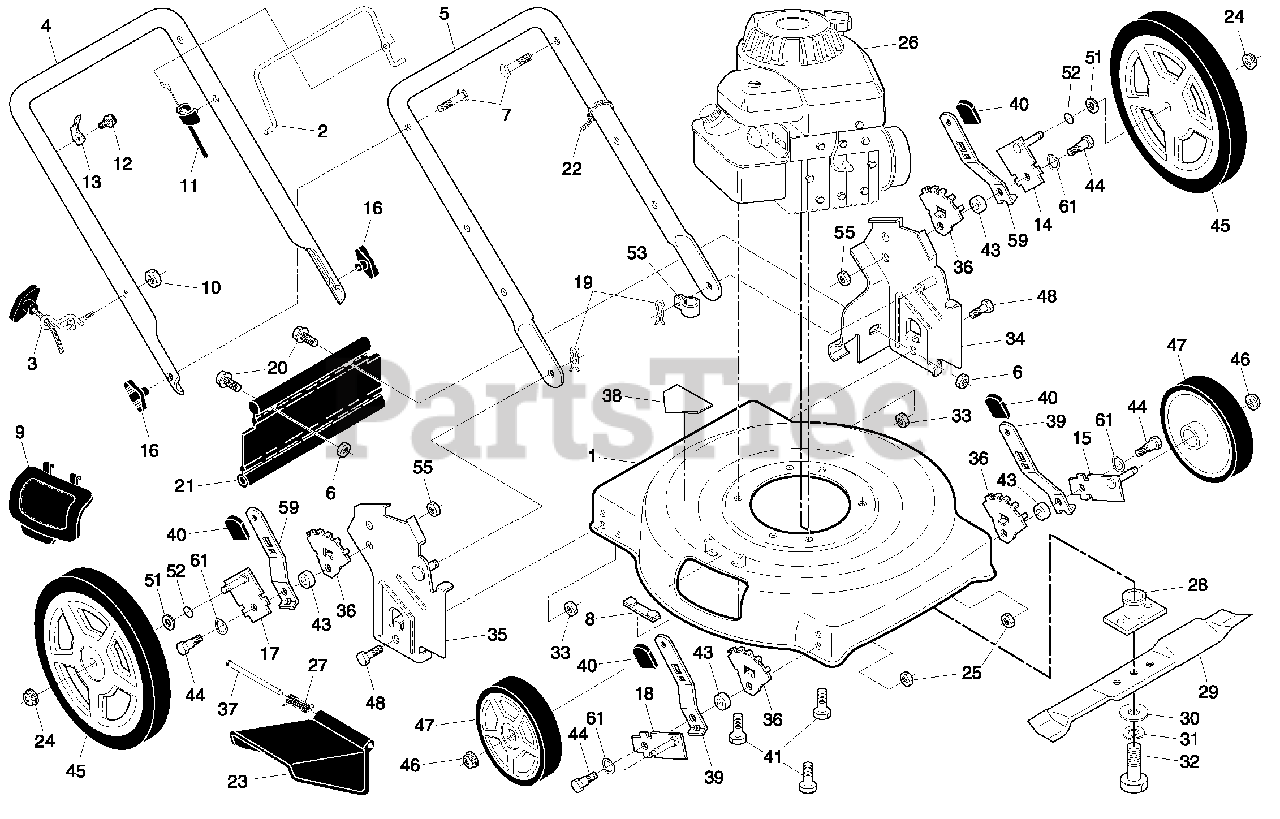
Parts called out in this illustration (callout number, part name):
1	Lawn Mower Housing
2	Control Bar
3	Rope Guide
4	Upper Handle
5	Lower Handle
6	Locknut, Hex 1/4-20
7	Handle Bolt 5/16-18
8	Clip, Closeout
9	Mulcher Plate
10	Nut, Hex 1/4-20
11	Engine Zone Control Cable
12	Hex Washer Head Screw #10-24 x 1/2
13	Up-Stop Bracket
14	Axle Arm Assembly, Rear, LH
15	Axle Arm Assembly, Front, LH
16	Knob, Handle
17	Axle Arm Assembly, Rear, RH
18	Axle Arm Assembly, Front, RH
19	Hairpin Cotter
20	Screw, Hex Cap Head 1/4-20
21	Rear Deflector
22	Wire Tie
23	Discharge Guard
24	Nut, Hex, Flangelock 3/8-16
25	Nut, Hex, Flangelock 5/16-18
27	Torsion Spring
28	Blade Adapter
29	22" Blade
30	Hardened Washer
31	Helical Lockwasher 3/8
32	Screw, Hex Head, Grade 8, 3/8-24 x 1-3/8
33	Nut, Hex, Nylock 5/16-18
34	Handle Bracket, LH
35	Handle Bracket, RH
36	Wheel Bracket Adjuster
37	Hinge Rod
38	Danger Decal
39	Selector Spring, Front
40	Selector Knob
41	Screw, Hex Head, Threaded, Rolled 3/8-16 x 1
43	Spacer
44	Shoulder Bolt 5/16-18
45	Wheel & Tire Assembly, Rear, 12"
46	Nut, Hex, Flangelock 3/8-16
47	Wheel & Tire Assembly, Front, 7"
48	Bolt, Hex Head 5/16-18
51	Washer, Flat 3/8
52	O-Ring
53	Clip, Cable
55	Nut, Hex
59	Selector Spring, Rear
61	Washer, Curved, Cylindrical
61	Operator’s Manual, English
61	Operator’s Manual, Spanish
61	Repair Parts Manual
